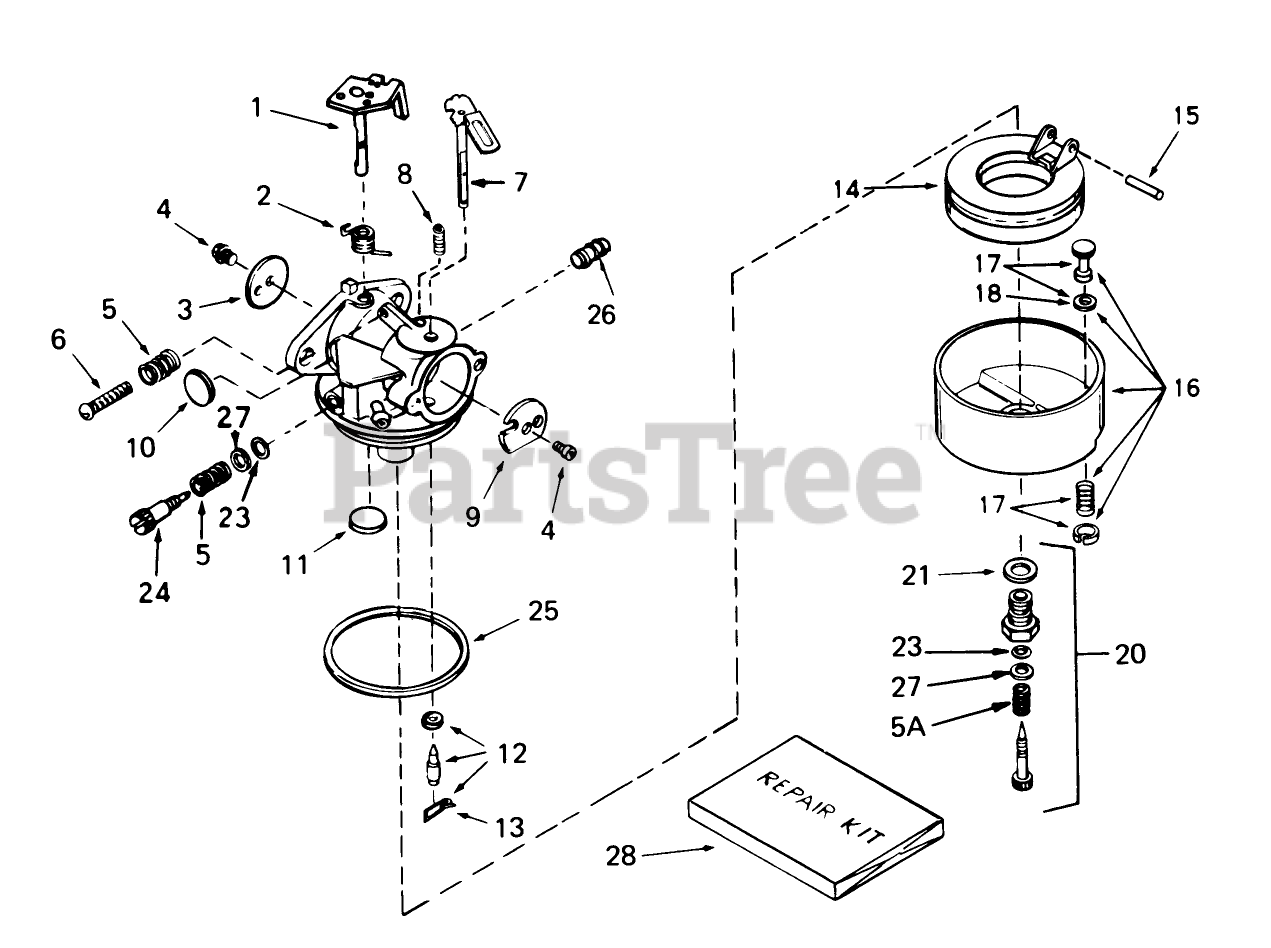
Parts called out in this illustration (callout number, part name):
1	Throttle Shaft and Lever ASM
2	Spring-Return, Throttle
3	Shutter-Throttle
4	Screw-Shutter
5	Spring-Regulating Screw
5A	Spring-Adjustment Screw
6	Screw-Idle Regulating
7	Choke Shaft and Lever ASM
8	Spring-Positioning, Choke
9	Shutter-Choke
10	Plug-Welch, Idle Mixture Well
11	Plug-Welch, Atmospheric Vent
12	Inlet Needle, Seat Clip Assy. (Incl. No. 13)
13	Clip-Spring
14	Float
15	Shaft-Float
16	Float Bowl Asm. (Incl. Ref. # 32, 33)
17	Bowl Drain ASM
18	Gasket-Plunger, Drain
20	Adjustment Screw Assy.,Main (Incl. Ref. #5A,21,23 30)
21	Washer-Bowl Nut
23	ORing
24	Screw-Idle Mix
25	O Ring-Bowl, Float
26	Fitting-Fuel
27	Washer
28	Kit-Repair
